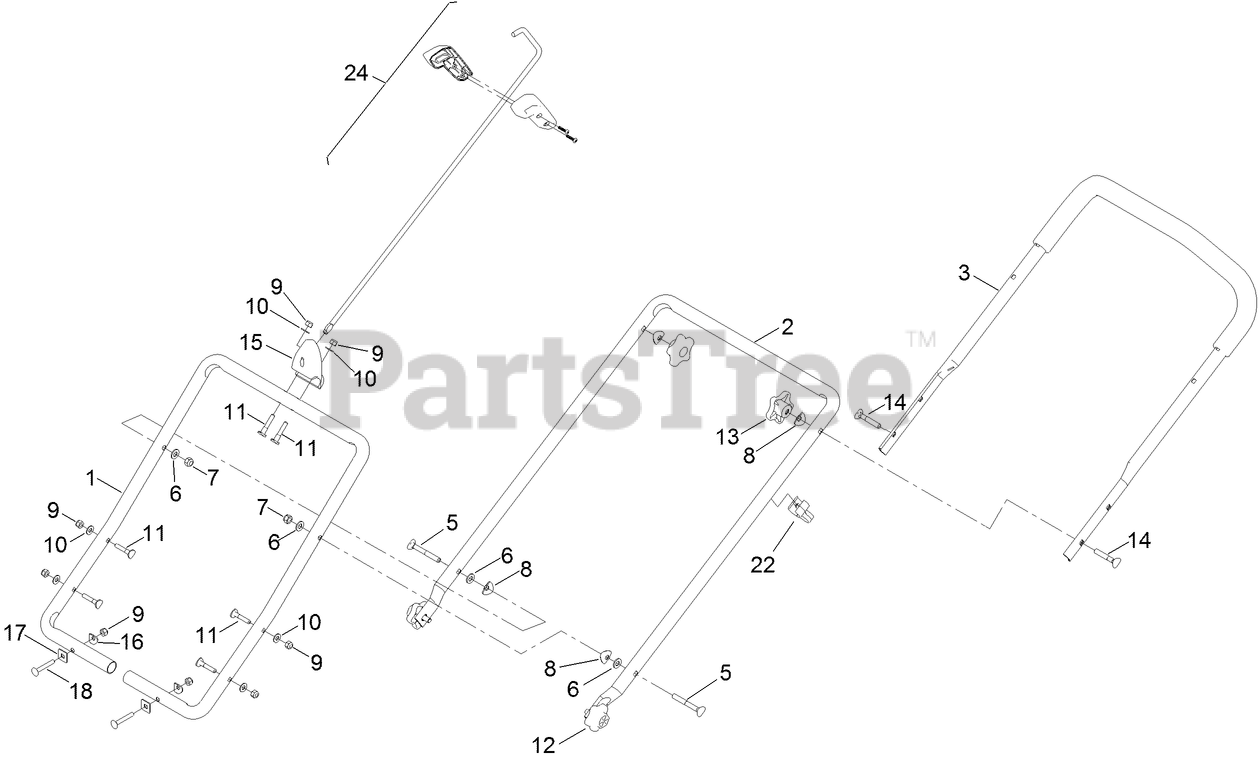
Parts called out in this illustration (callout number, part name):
1	HANDLE-LOWER
2	HANDLE-MIDDLE
3	UPPER HANDLE ASM
5	SCREW-HANDLE
6	WASHER-FLAT
7	NUT-LOCK, NI
8	WASHER
9	NUT-LOCK, NI
10	WASHER-FLAT
11	SCREW-HANDLE
12	KNOB-HANDLE
13	KNOB-HANDLE
14	SCREW-HANDLE
15	GUIDE-ROD, CHUTE
16	WASHER
17	WASHER-SQUARE
18	SCREW-CARR
22	GUIDE-CABLE
24	HANDLE ASM
